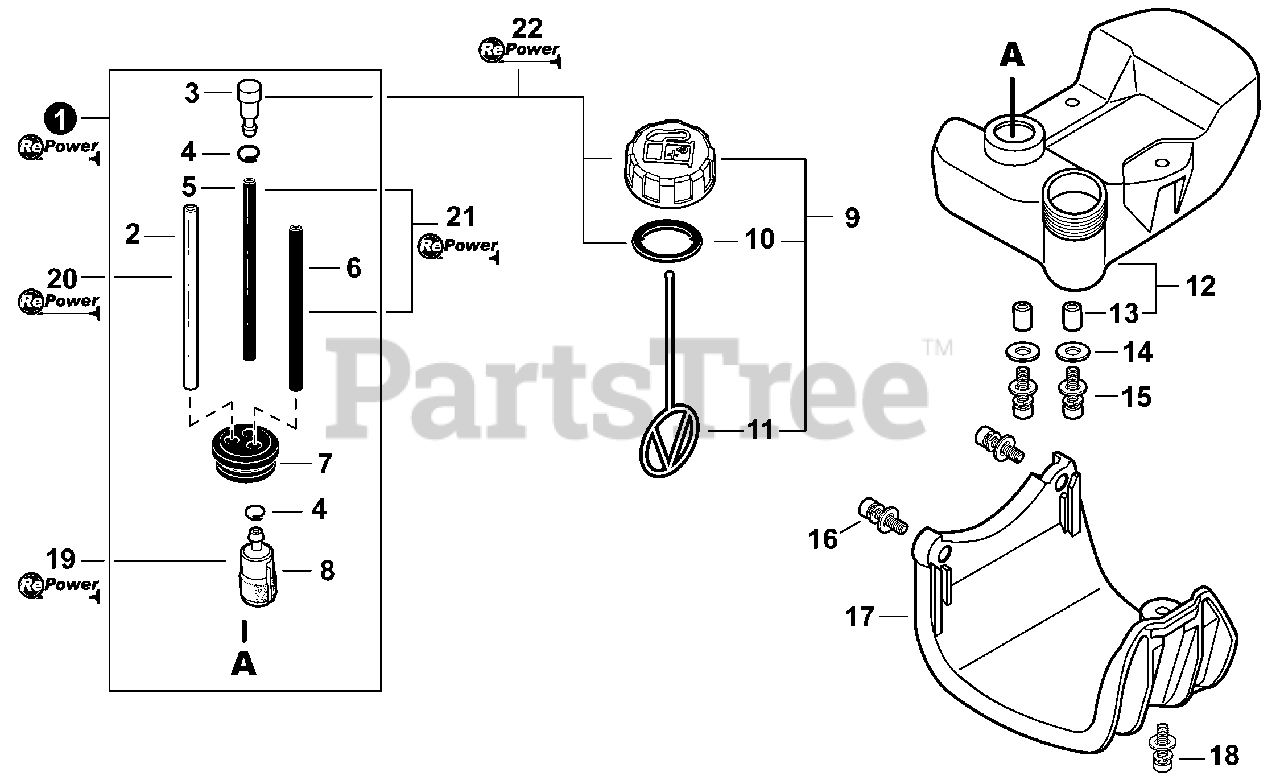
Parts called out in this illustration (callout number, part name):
1	FUEL SYSTEM KIT - REPOWER
2	PIPE, FUEL 3×6×80 CLEAR
3	VENT ASSY
4	CLIP 6.5MM
5	PIPE, FUEL 3×6×115 BLACK
6	PIPE, FUEL 3×6×170
7	GROMMET, FUEL
8	FILTER, FUEL
9	CAP ASSY, FUEL
10	GASKET, FUEL CAP
11	CONNECTOR, CAP L= 100mm
12	TANK, FUEL
13	SPACER 6.2×7.8×6
14	WASHER 5.5×12×0.8
15	BOLT 5×16
16	BOLT 5×22
17	GUARD, FUEL TANK
18	SCREW 5×20
19	TUNE-UP KIT - REPOWER
20	PIPE, BULK - 3×6mm CLEAR
21	PIPE, BULK - 3×6mm BLACK
22	CAP/VENT KIT - REPOWER
